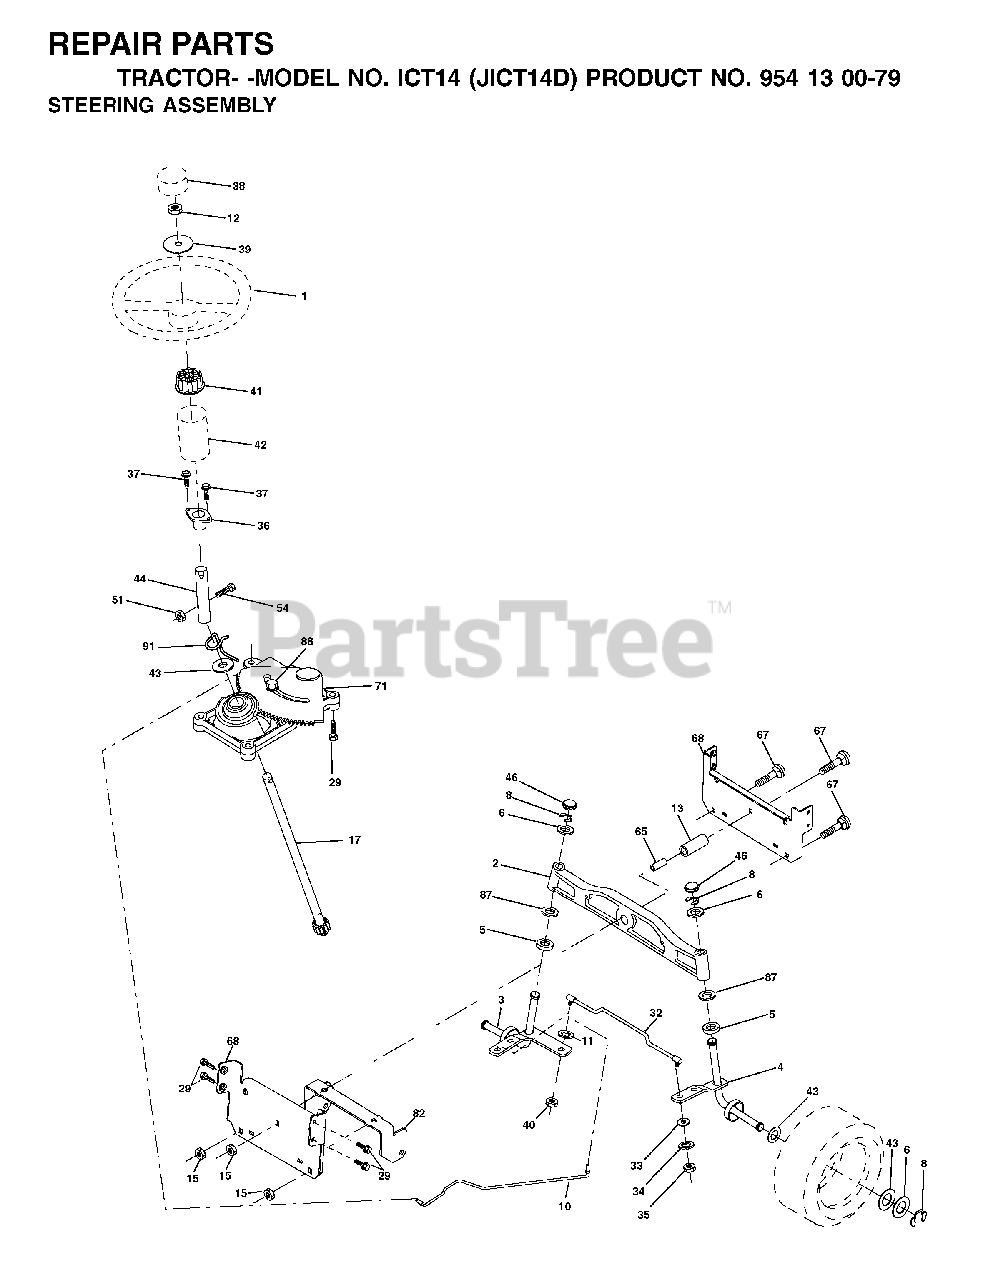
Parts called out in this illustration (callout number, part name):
2	AXLE ASM
3	SPINDLE.ASM.LH.15"TIRES
4	SPINDLE.ASM.RH.15"TIRES
8	RING CLIP
10	DRAGLINK.15".TIRES.2001
11	WASHER, LOCK 3/8
12	NUT.HEX.1/2-20
13	TUBE, PIVOT AXLE
15	NUT
17	SHAFT ASM, STEERING
29	SCREW 3/8-16X3/4
32	ROD.ASM.TIE.BALL.JOINT.NOVAN
33	WASHER M
34	LOCKWASHER
35	NUT, CROWNLOCK
36	BUSHING, STEERING
40	GRIPCO NUT
41	STEERING WHEEL ADAPTOR
42	BOOT.STEERING.SHAFT.BLACK
44	EXT, STEERING SHAFT
46	CAP.SPINDLE
51	CROWN LOCKNUT
65	SPACER BRACE AXLE
67	BOLT
68	BRACE.AXLE.15"TIRES
71	STEERING ASM
82	BRACKET
87	WASHER, FLAT .781 X 1 1/2"
88	BOLT, SHOULDER 7/16-20
91	CLIP.STEERING
